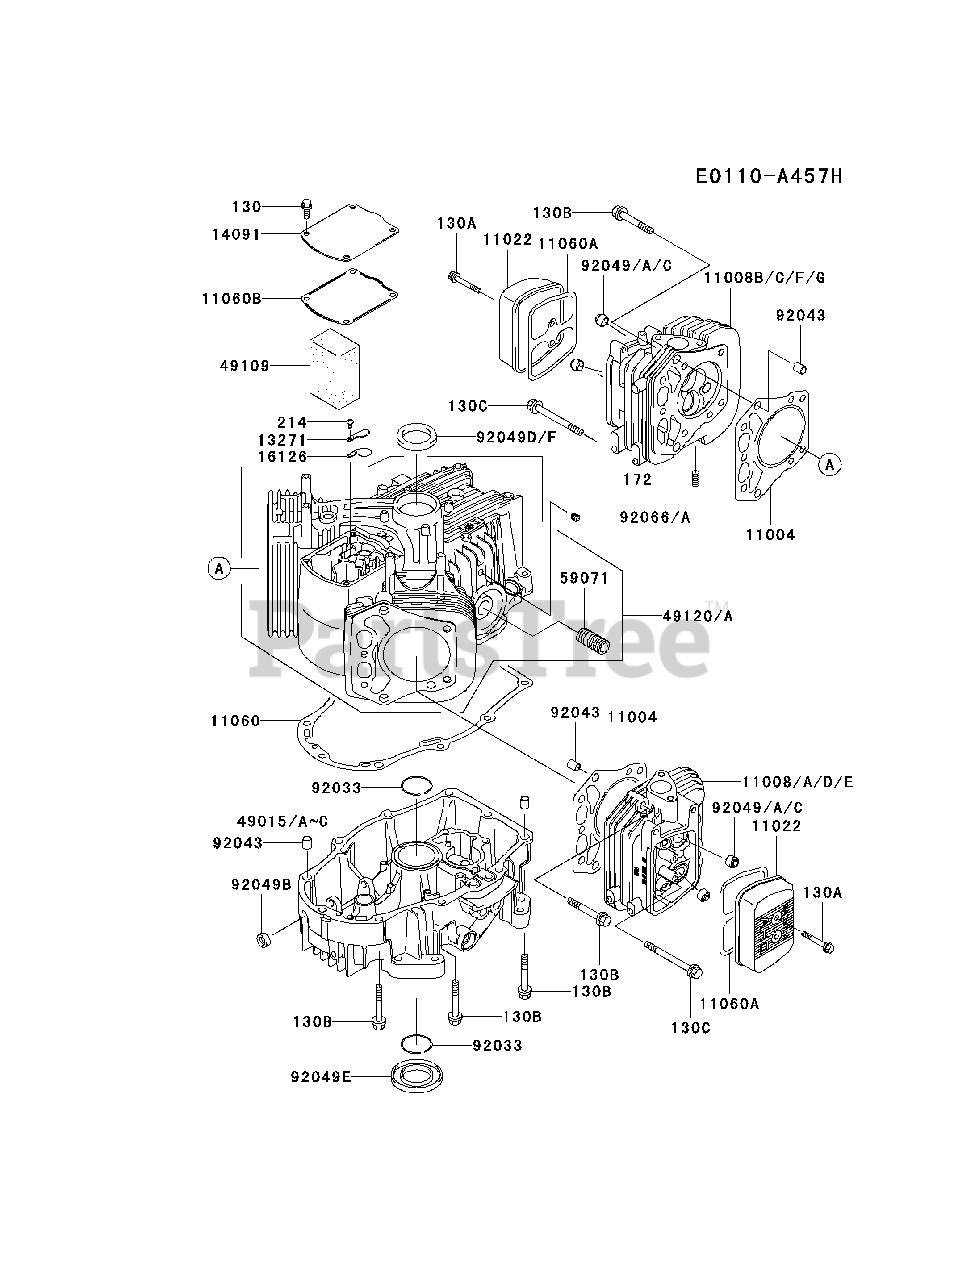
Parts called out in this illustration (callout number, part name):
130	BOLT-FLANGED
130A	BOLT-FLANGED
130B	BOLT-FLANGED
130C	BOLT-FLANGED
172	BOLT-STUD
214	SCREW-PAN+-
